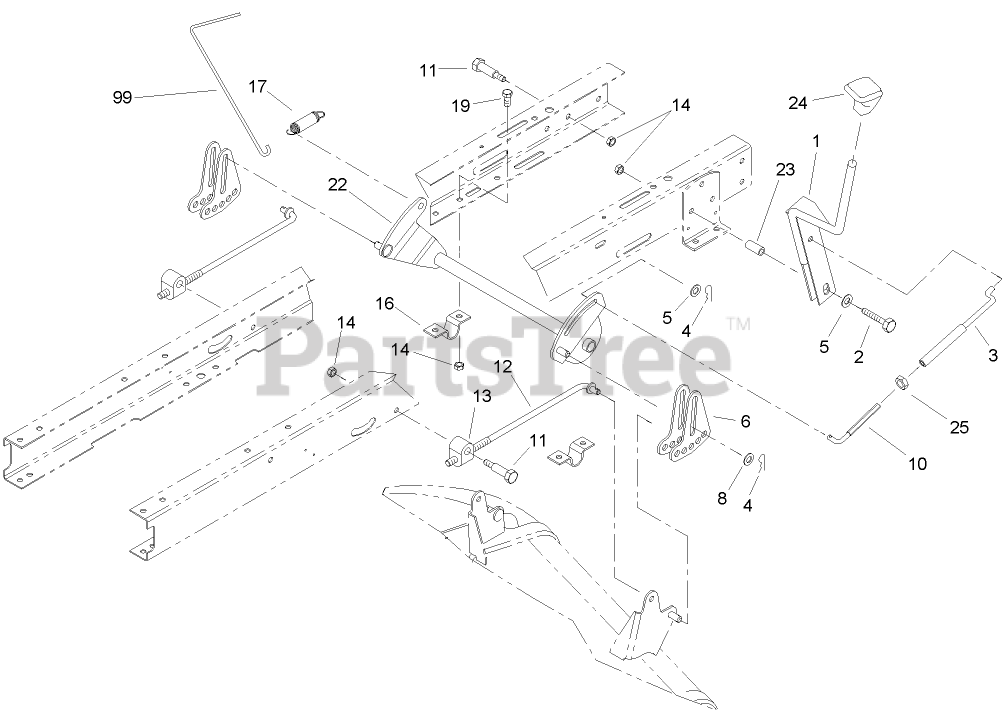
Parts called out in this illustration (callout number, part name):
2	SCREW-HH
3	HOC LINKAGE (WELDMENT)
5	WASHER-FLAT
6	LINK-ADJUSTING, HOC
8	WASHER-HARDENED
10	LINKAGE-HOC
11	SCREW-SHOULDER, HH
12	ROD-HANGER, REAR
13	TRUNNION-HOC
14	NUT-LOCK, NI
16	CLAMP-PIVOT, HOC
17	SPRING-EXTENSION
19	SCREW-HH
22	HOC PIVOT ASM (BLACK)
23	SPACER
24	KNOB-SHIFT
25	NUT-JAM
99	TOOL-SPRING
